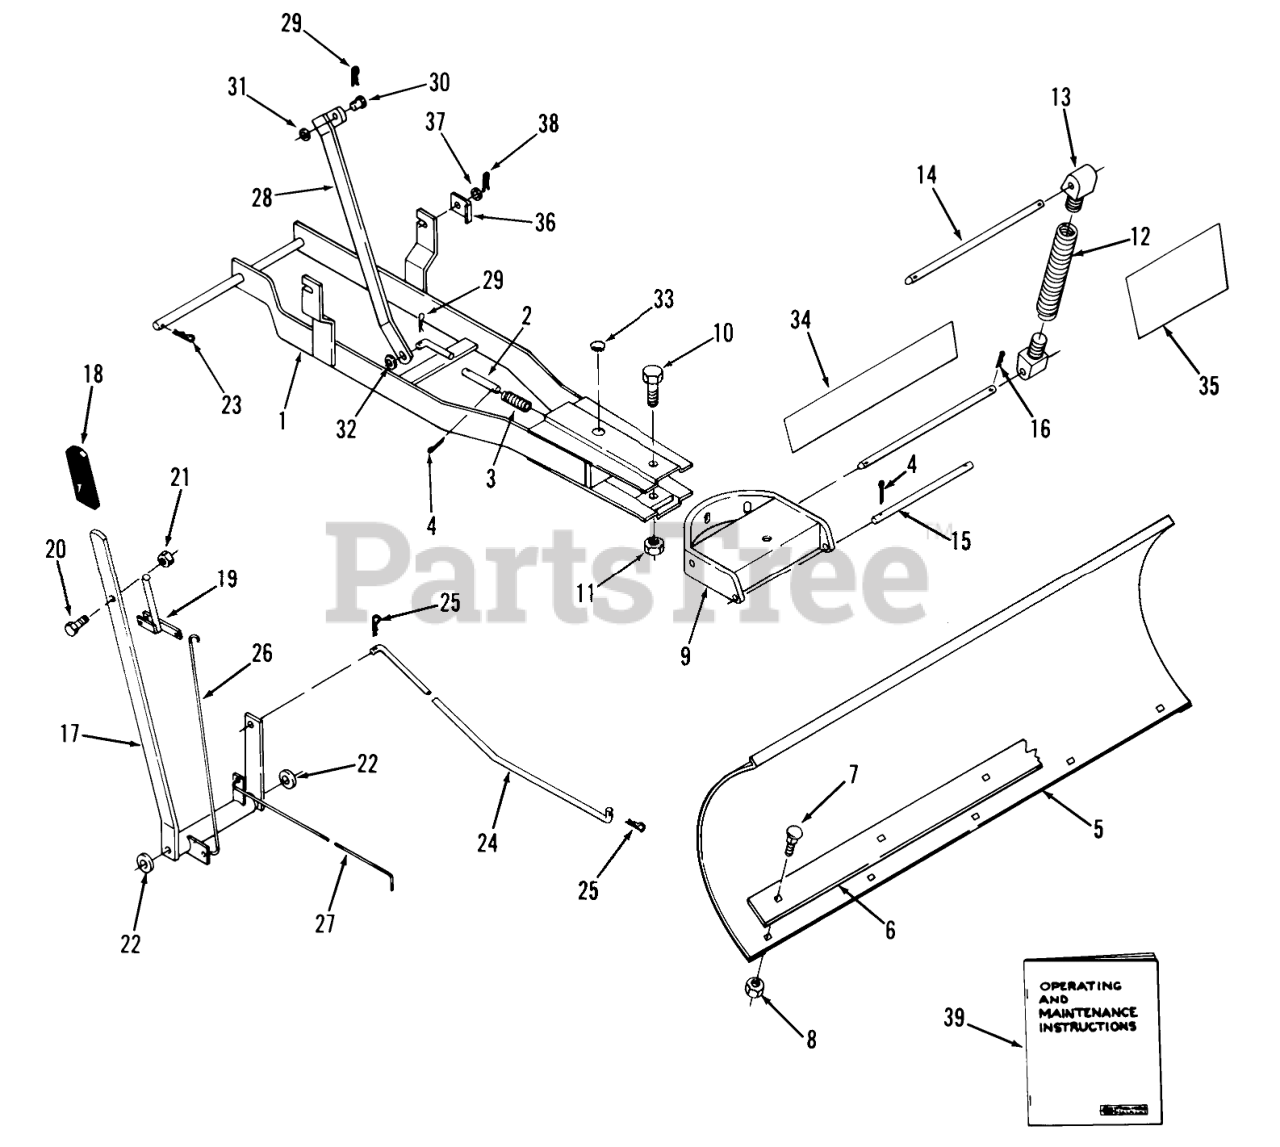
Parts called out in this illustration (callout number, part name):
1	Frame
2	Index Pin
3	SPRING-COMPRESSION
5	Blade
6	Plate
7	Bolt-Carriage
8	NUT
9	Sector and Channel
10	Bolt
11	Nut
12	Spring
13	Lug
14	ROD-PIVOT, BLADE
15	ROD-LOWER
16	Hairpin
17	Index Lever
18	GRIP
19	LEVER ASSY
20	Bolt
21	Nut
22	Washer
23	Hairpin
24	Brake Pedal
25	Hairpin
26	Upper Index Rod
27	LOWER INDEX ROD
28	Lift Bar
29	Hairpin Cotter
30	PIN
31	Washer
32	WASHER
33	PLUG
34	DECAL-WHEEL HORSE
35	Caution Decal
36	CLIP
37	Washer
38	Hairpin Cotter
39	OPERATOR MANUAL
